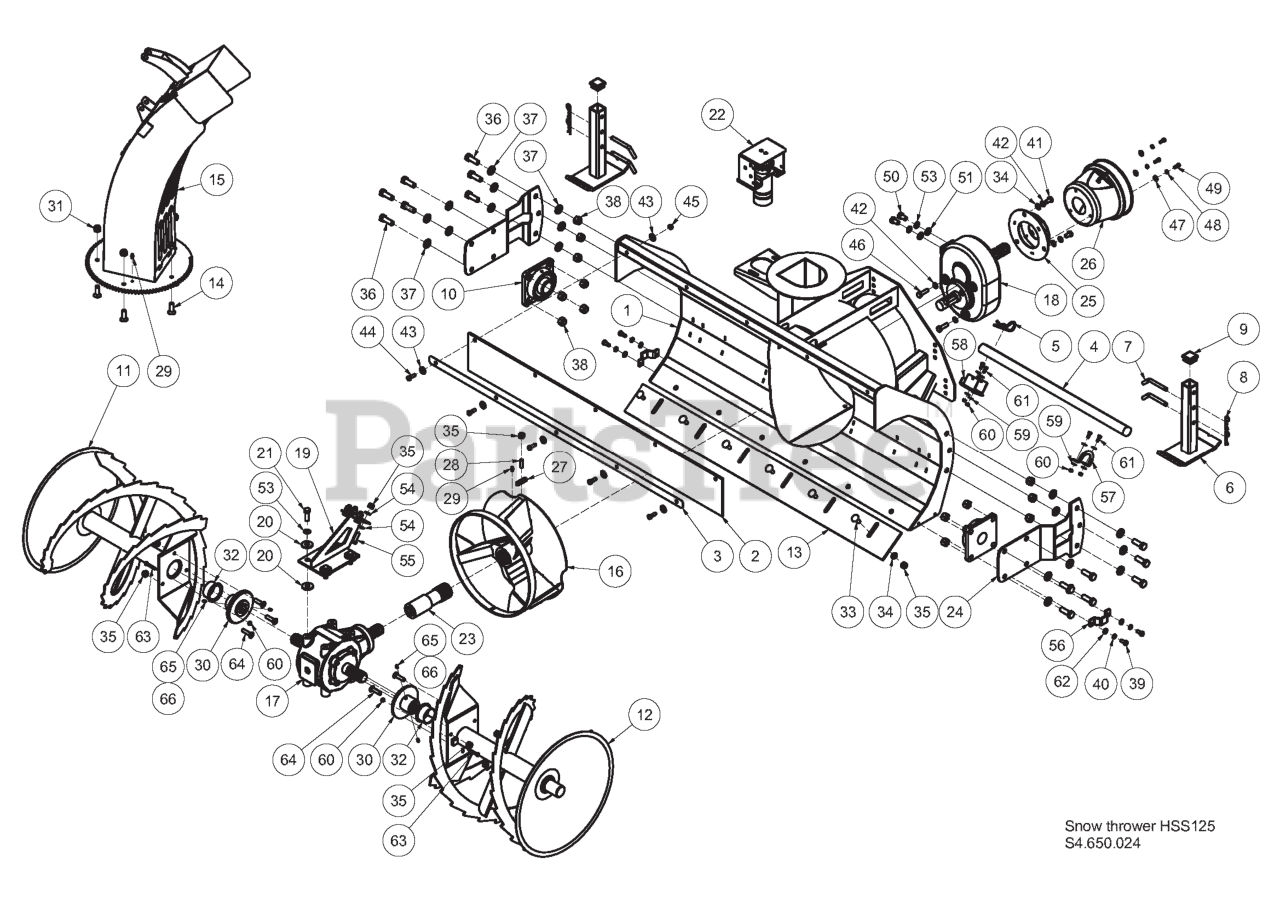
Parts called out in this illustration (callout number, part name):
10	BEARING UCF 208-DIA.40MM
14	SCREW M10X30
19	MOUNTING BRACKET
28	SCREW M10X30
32	BEARING RING
34	WASHER
35	NUT
44	SCREW M6S 8X25
45	LOCKNUT M8
47	WASHER - 26X6.5X1.6
51	COVER WASHER
52	SPRING WASHER
54	WASHER
60	LOCKNUT M6
61	Screw
62	WASHER BRB 8.4X17
65	STOP SCREW
